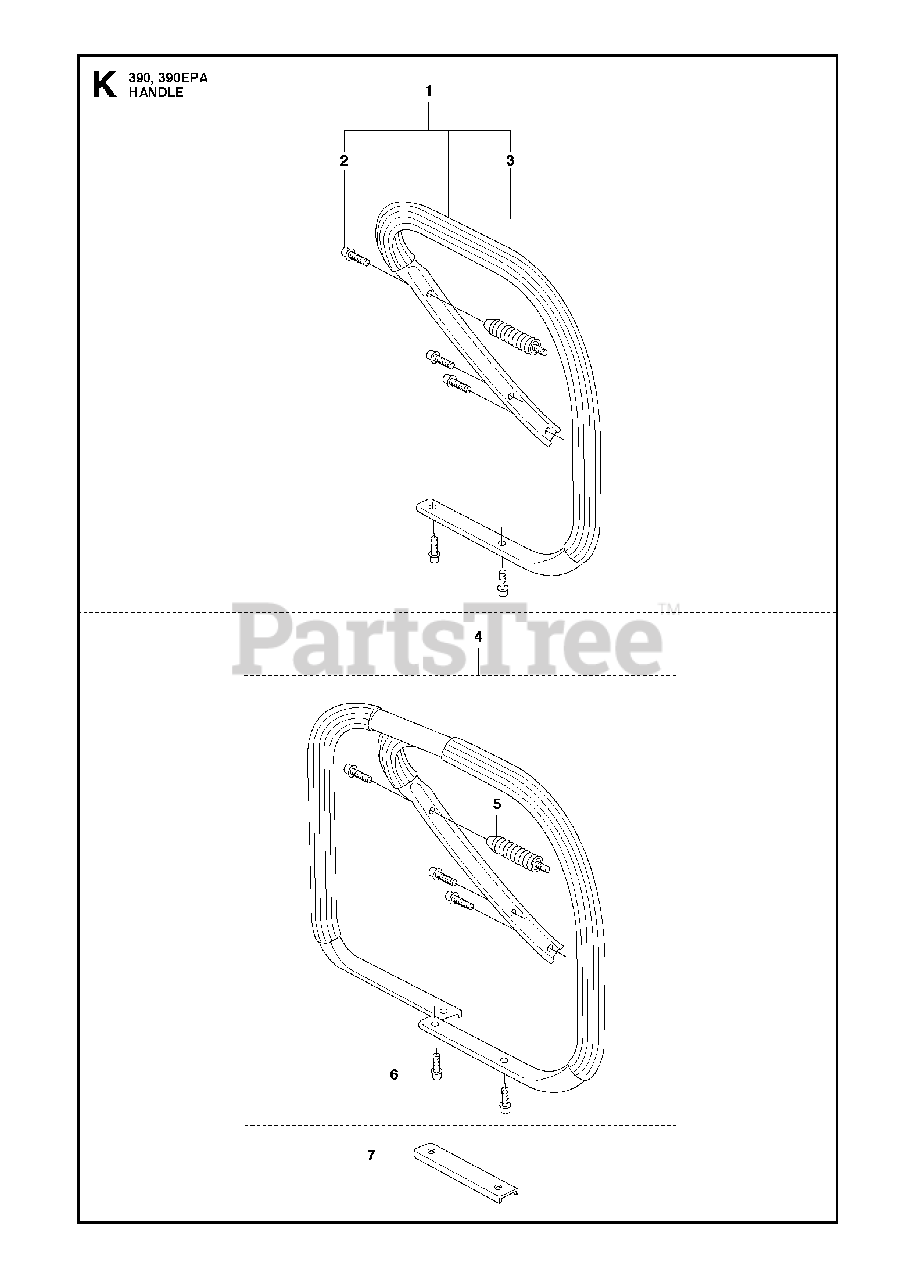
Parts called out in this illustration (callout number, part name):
1	FRONT HANDLE
2	SCREW
3	SPRING
4	HANDLE
5	SPRING
5	VIBRATION ABSORBER
6	SCREW
7	PLATE
